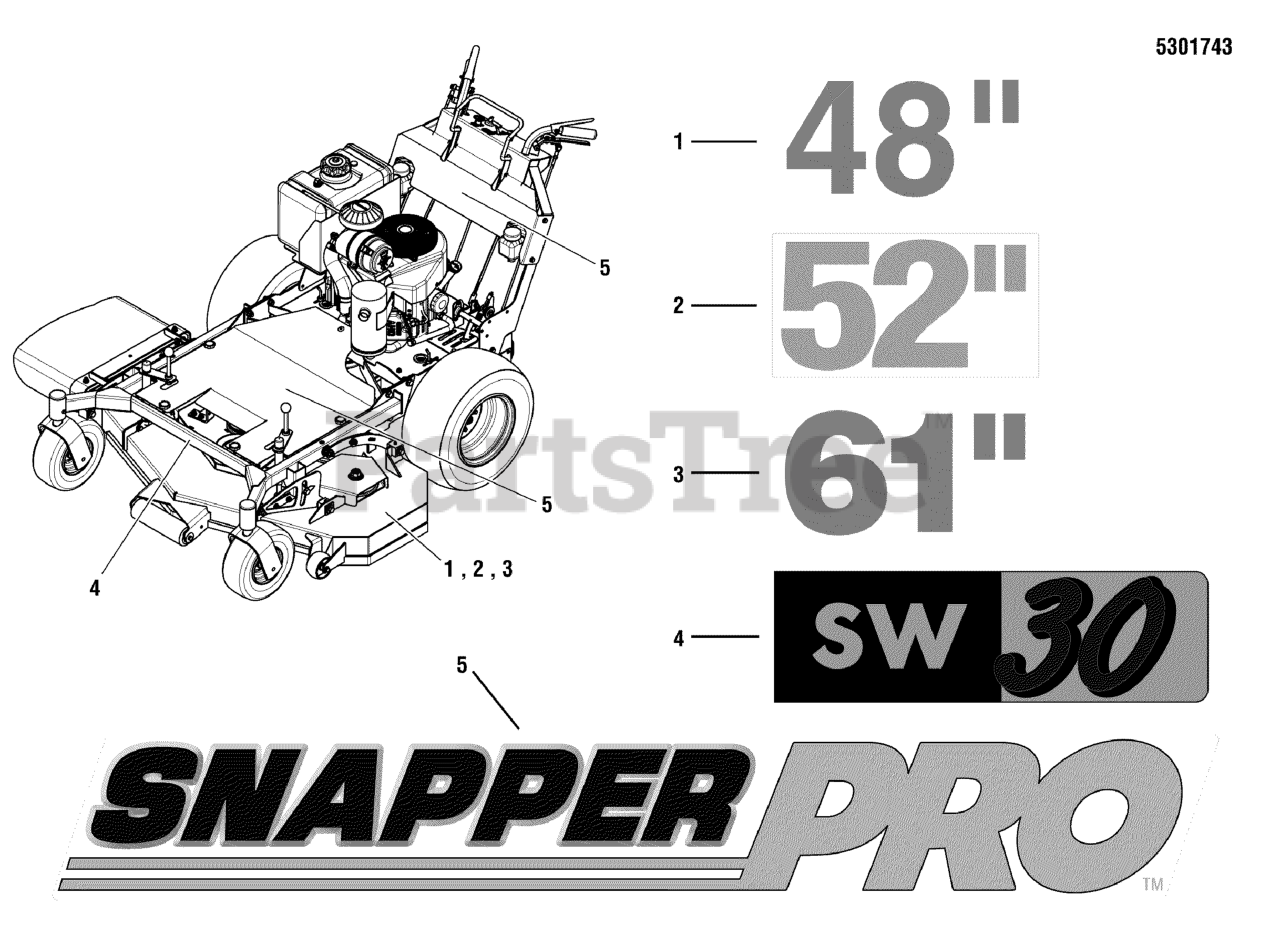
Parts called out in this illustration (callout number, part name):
1	DECAL, 48
2	DECAL, 52
3	DECAL, 61"
4	DECAL, SW30
5	DECAL, SNAPPER PRO, FRONT
